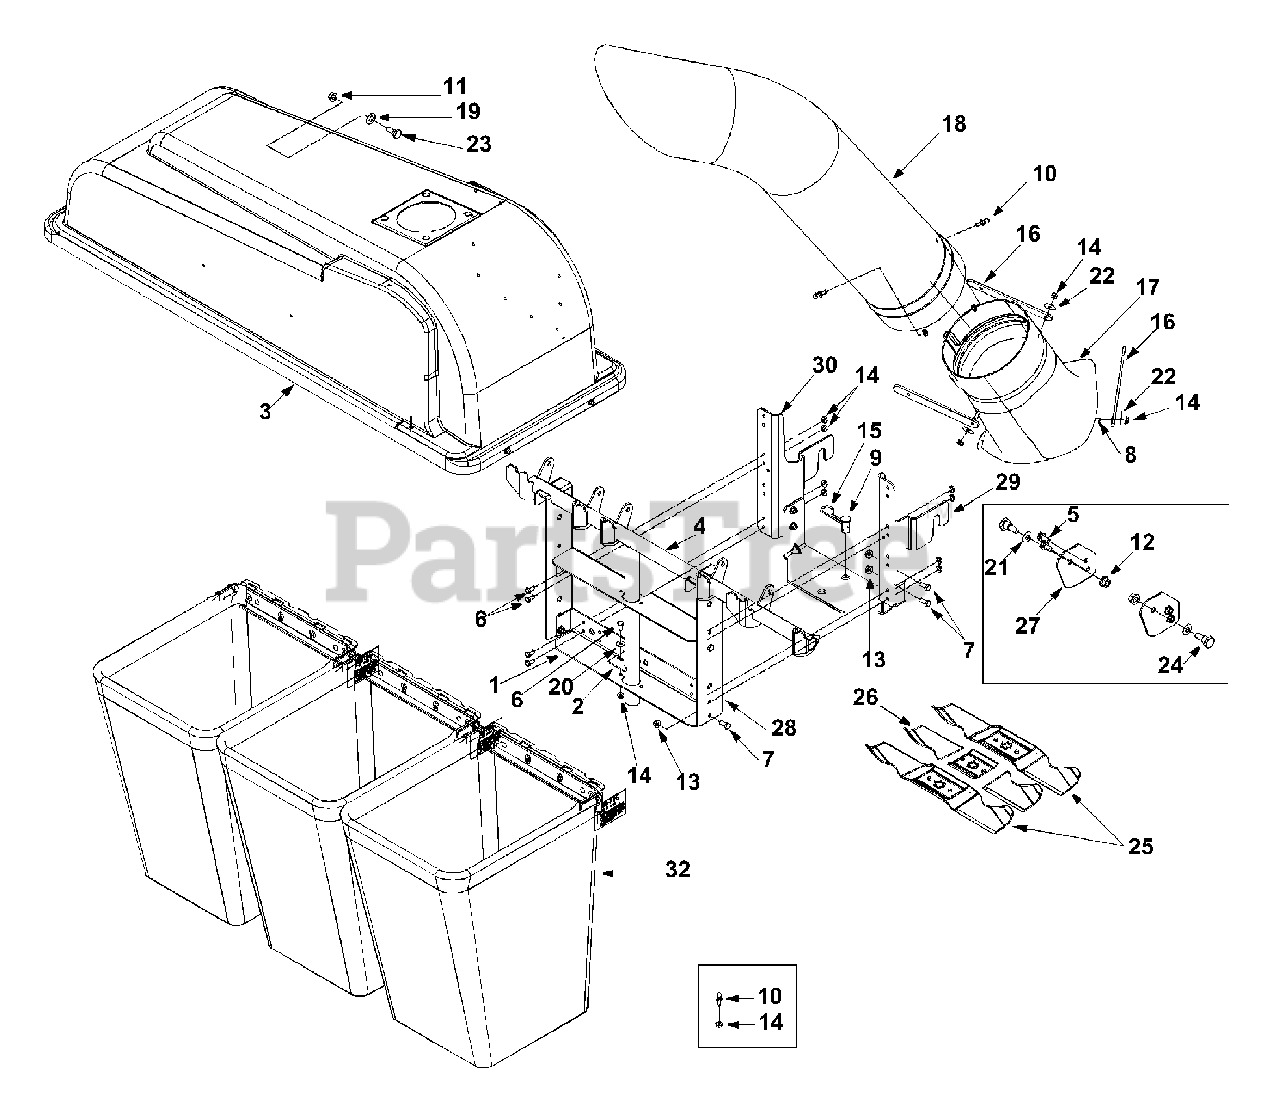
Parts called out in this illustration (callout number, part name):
3	Grasscatcher Cover Assembly
6	Hex Screw 1/4-20 x 0.620
7	Hex Screw 5/16-18 x 0.75
8	Hex Screw 1/4-20 x 0.75
10	Grasscatcher Pin
11	Flange Lock Nut 3/8-16
12	Lock Nut 7/16-20
13	Lock Nut 5/16-18
14	Lock Nut 1/4-20
15	Hairpin Clip
16	Chute Strap
17	Discharge Chute Elbow
19	Beleville Washer
20	Beleville Washer
23	Shoulder Screw
24	Shoulder Screw
25	Blade 16.28"
26	Blade 14.88"
32	Bag Assembly: Triple Bagger
